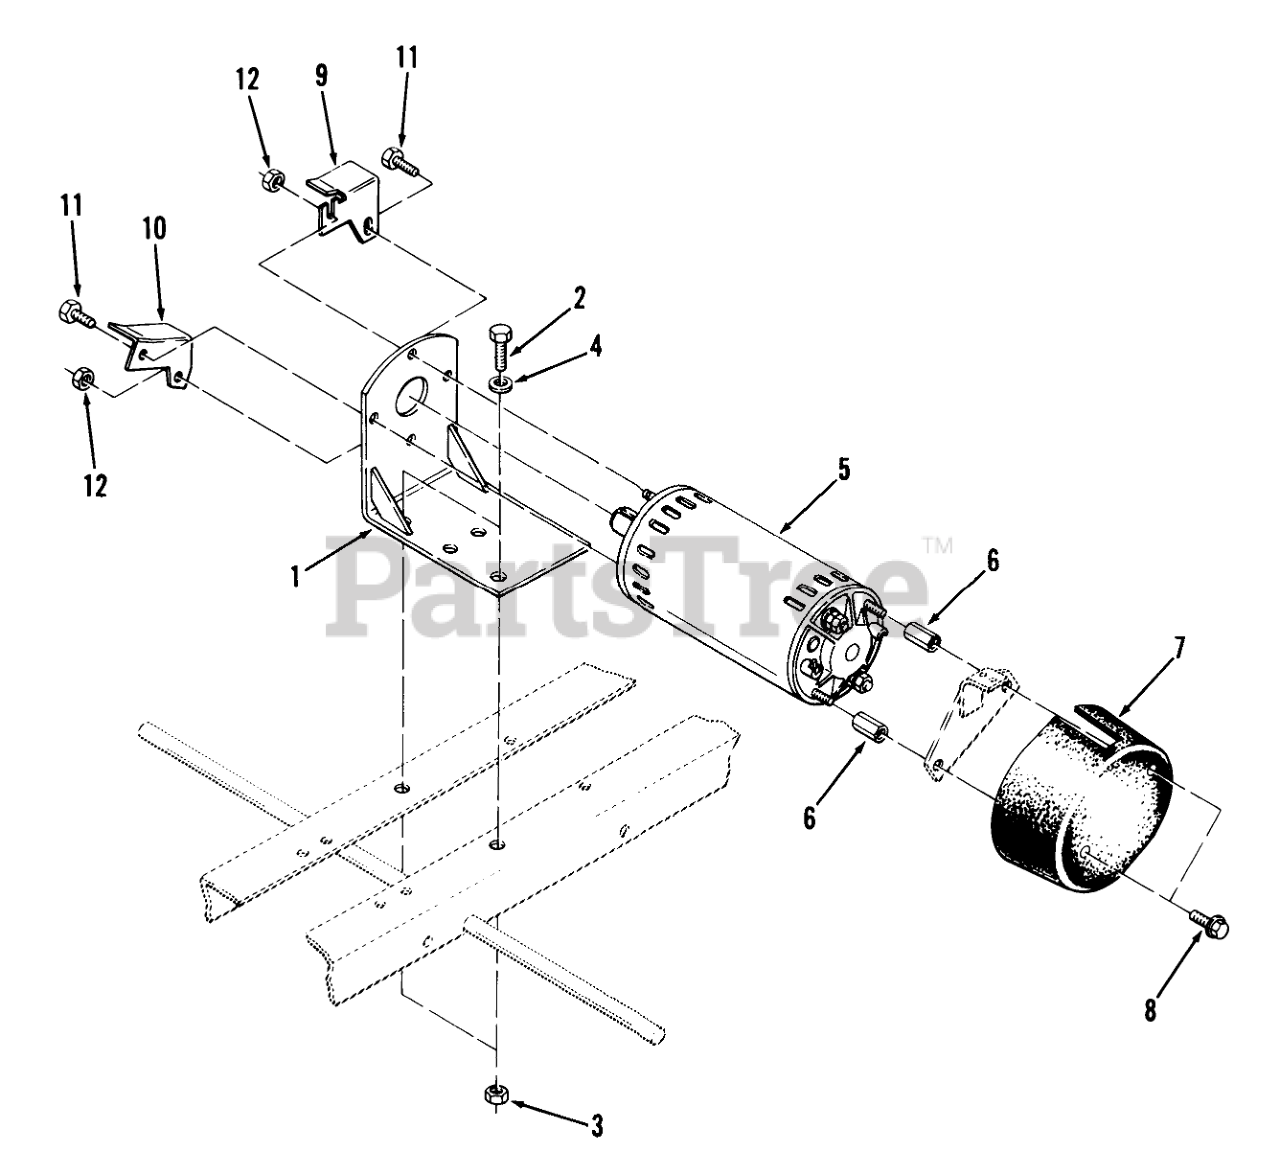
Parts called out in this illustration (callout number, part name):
1	MOTOR MOUNT ASSY
2	Bolt
3	Nut
4	Washer
5	Drive Motor
6	Spacer
7	Motor Cover
8	Whizlock Bolt 5/16-18 X 3/8
9	Belt Guard-Upper
10	Belt Guard-Lower
11	Bolt
12	Nut
